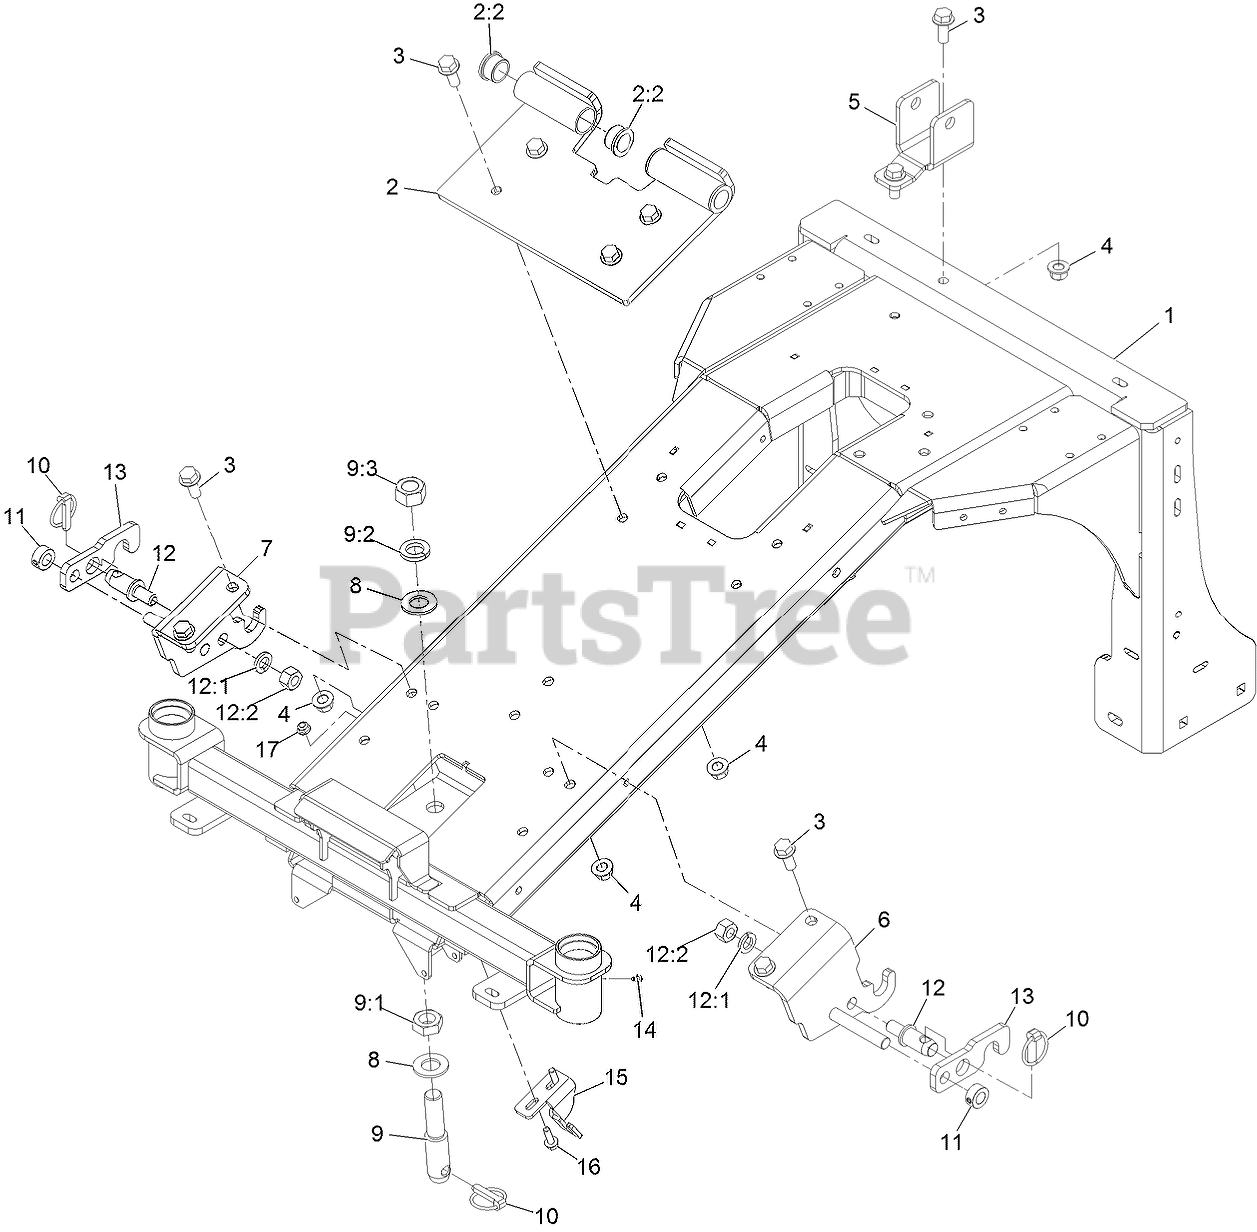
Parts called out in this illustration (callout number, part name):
1	FRONT FRAME ASM
2	PIVOT-ARM, LIFT ASM
2:2	BUSHING-FLANGE
3	SCREW-HHF
4	Nut-Lock 1/2-13
5	BRACKET-MOUNT, CYLINDER
6	X-REF 135-9471-05
7	HITCH PIN-RH
8	WASHER-FLAT
9	1-1/8 X 5-1/4 LIFT ARM PI
9:1	NUT-JAM
9:2	WASHER-LOCK/SP
9:3	NUT-HEX
10	PIN-LYNCH
11	5/8 SHAFT COLLAR
12	7/8 X 3-1/8 ANCHOR PIN (2
12:1	WASHER-LOCK
12:2	NUT-HEX
13	PLATE-ATTACHMENT, LOCK
14	FITTING-GREASE, ZERK
15	BRACKET-CABLE, LCS
16	SCREW-HH
17	NUT-HF, NI
